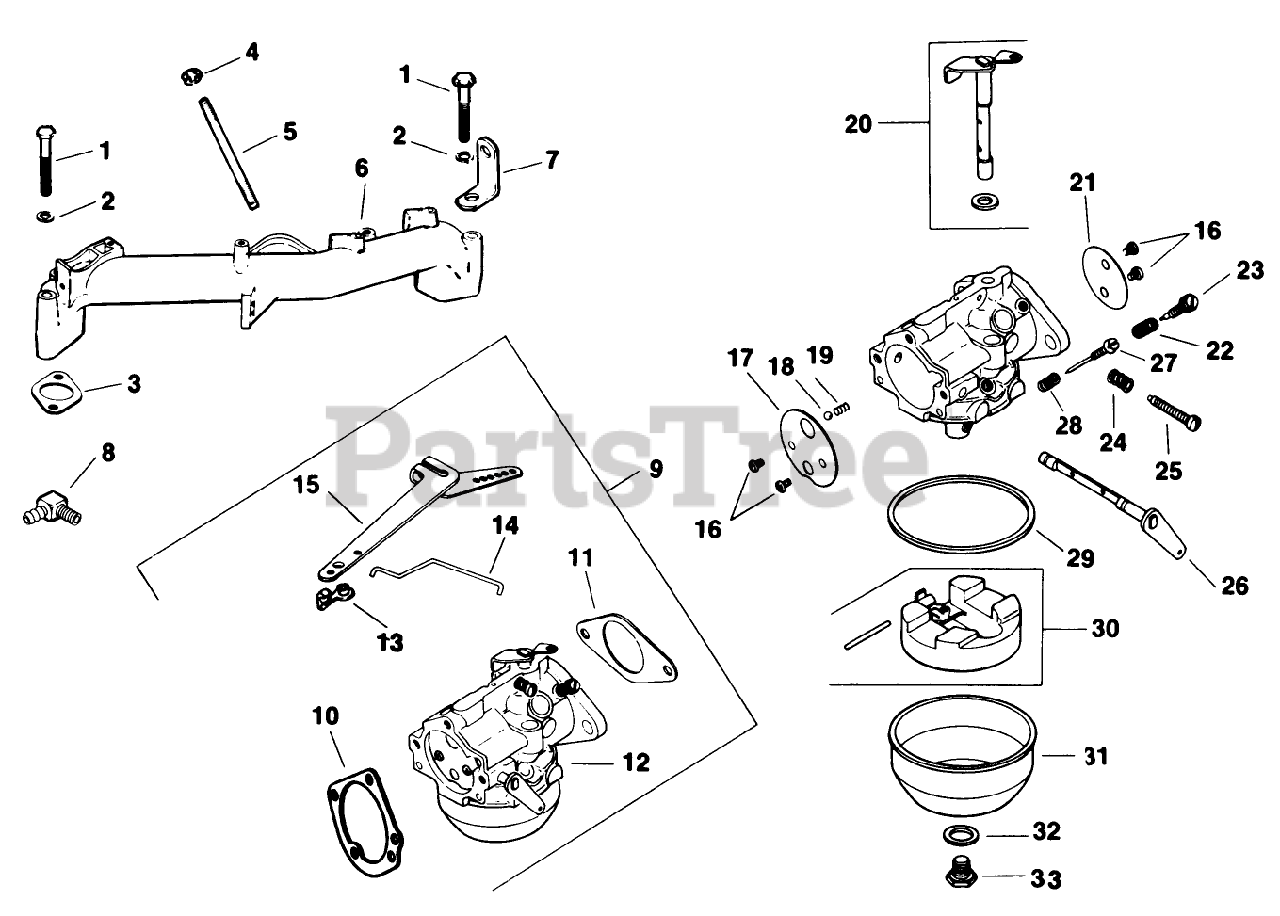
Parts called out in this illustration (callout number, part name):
1	Screw-H.C.
2	Washer
3	Gasket-Intake
4	Nut
5	Stud
6	Manifold-Intake
7	Strap-Lifting
8	Connector-90deg.
9	Kit-Carburetor w/Gasket (Incl. Ref. #10-33)
10	Gasket
11	Gasket
12	Carburetor
13	Bushing
14	Kit-Governor Linkage (Incl. Ref. #13)
15	Arm-Governor
16	Screw-Throttle Plate
17	Plate-Choke
18	Ball-Choke
19	Spring-Choke
20	Shaft-Throttle Lever & Sea
21	Plate-Throttle
23	Valve-Needle
26	Lever-Choke
27	Needle-Main Fuel
29	Bowl-Gasket
30	Kit-Float
32	Gasket-Bowl
33	Screw-Bowl
